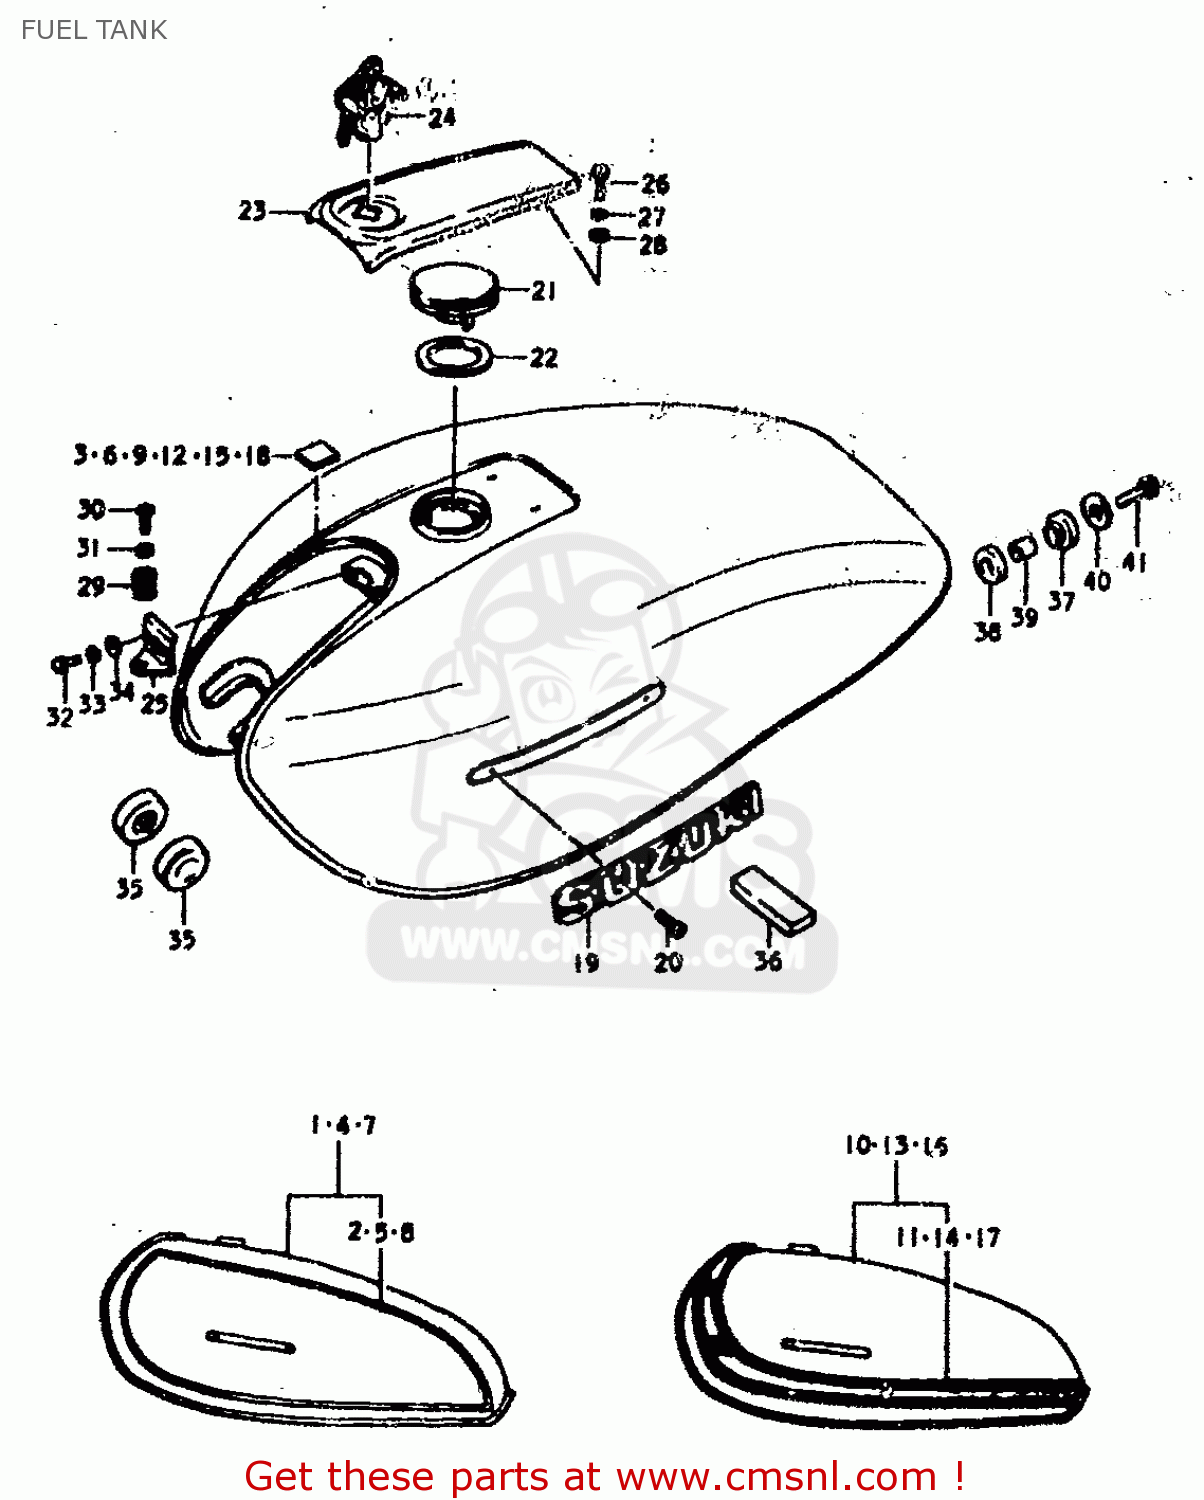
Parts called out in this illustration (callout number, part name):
10	TANK, FUEL
11	TAPE SET
12	CUSHION,FUEL TANK FR COVER
13	TANK, FUEL
14	TAPE SET
15	CUSHION,FUEL TANK FR COVER
16	TANK, FUEL
17	TAPE SET
18	CUSHION,FUEL TANK FR COVER
24	LOCK,FUEL TANK FR COVER
25	HOLDER,FUEL TANK FRONT COVER
26	BOLT
27	LOCK WASHER
28	WASHER
29	SPRING
30	SCREW
31	LOCK WASHER
32	BOLT
33	LOCK WASHER
34	WASHER 5MM
35	CUSHION
36	CUSHION
37	CUSHION
38	CUSHION
39	SPACER(8.5X12X19)
40	WASHER (8.5X29X1.6)
41	BOLT (8X30)
